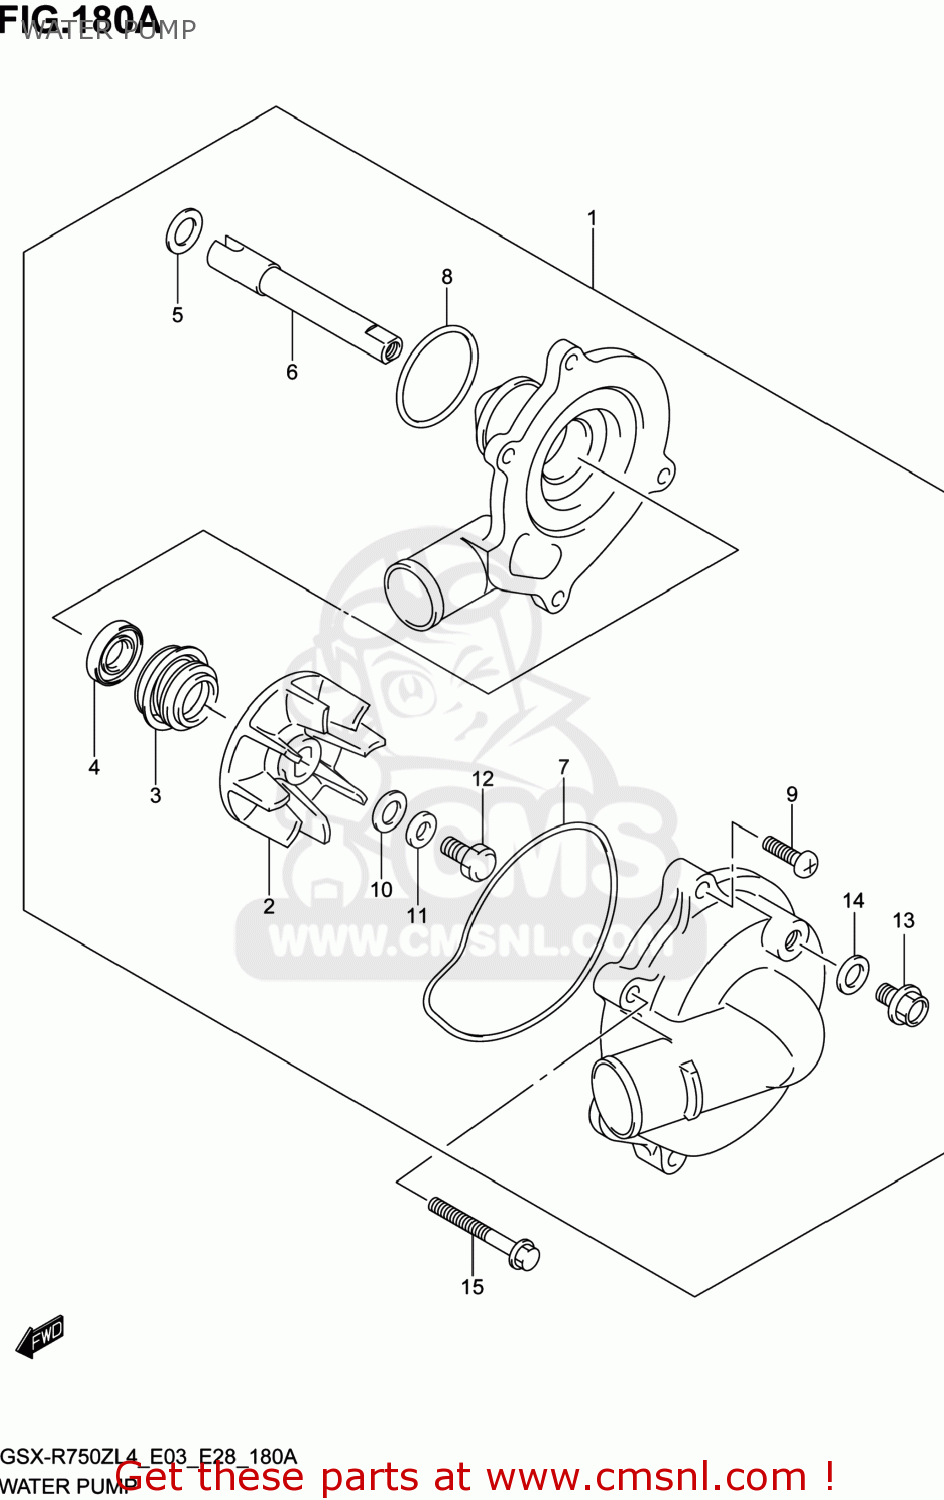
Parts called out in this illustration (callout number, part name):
1	PUMP ASSY,WATER
2	IMPELLER
3	SEAL,MECHANICAL
4	SEAL,OIL
5	WASHER
6	SHAFT
7	O RING
8	O RING,WATER PUMP HOLDER
9	SCREW
10	GASKET(6X15X2.2) (NAS)
11	WASHER
12	BOLT(6X13)
13	BOLT,DRAIN
14	GASKET(8.2X14X1) (NAS)
15	BOLT
